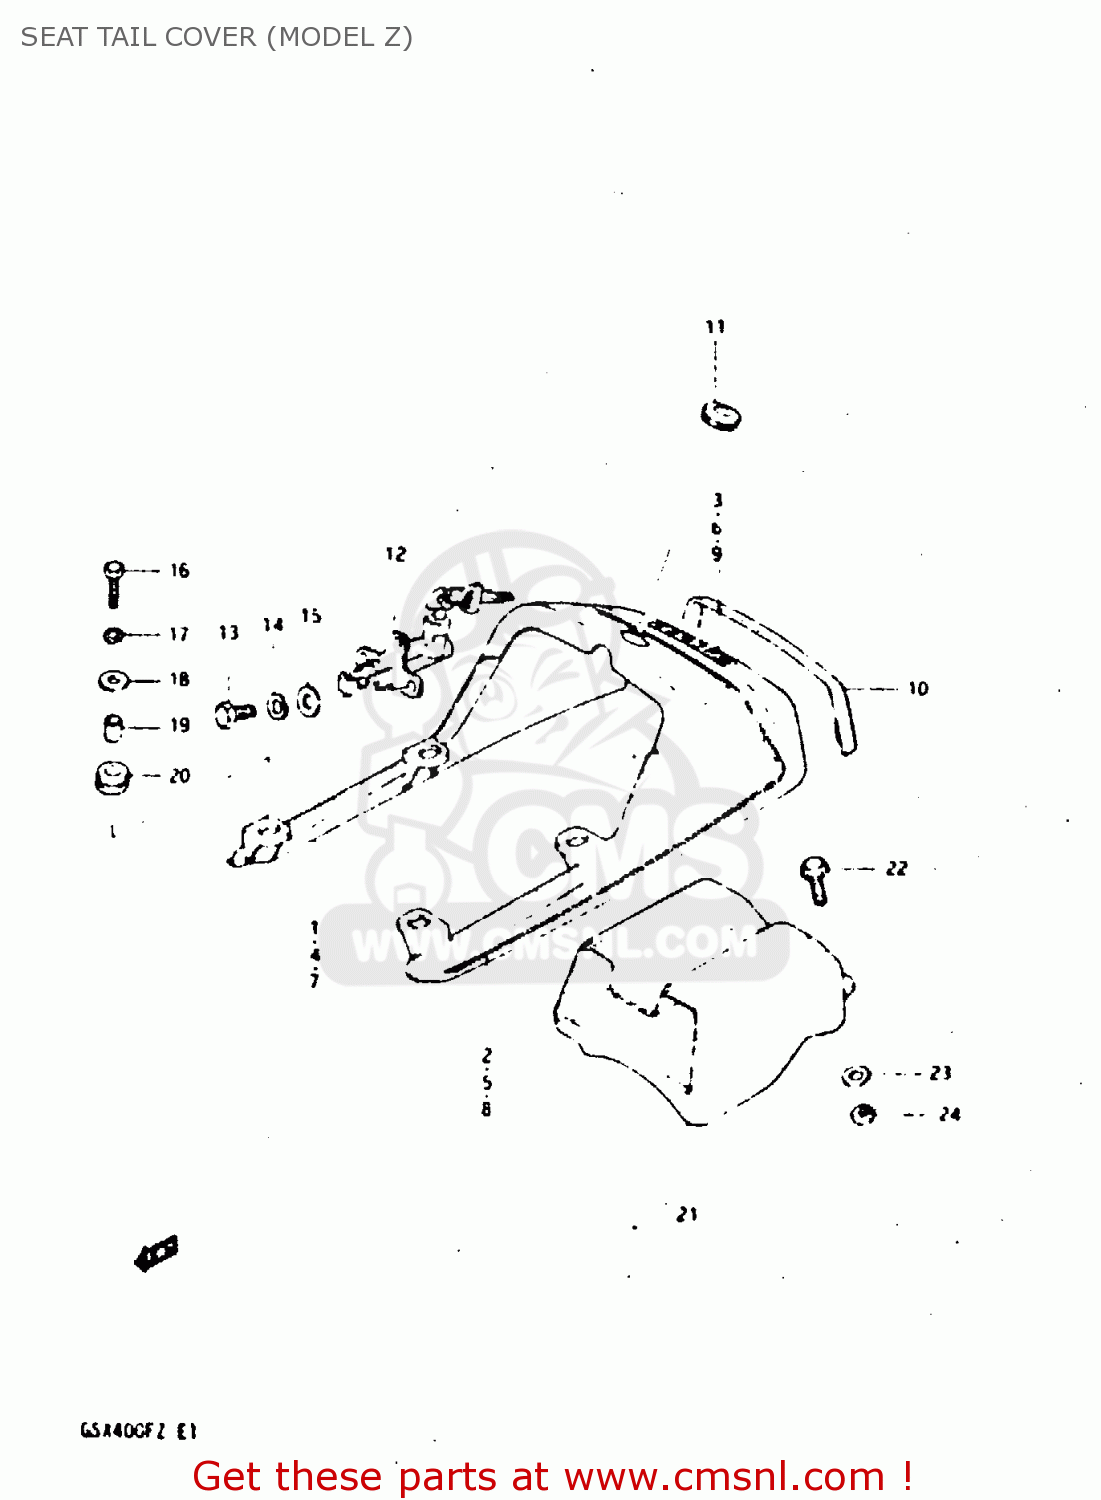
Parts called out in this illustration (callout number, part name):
1	COVER,SEAT TAI
2	TAPE SET
3	EMBLEM,SEAT TAIL(SILVER)
4	COVER, SEAT TAIL (SILVER)
5	TAPE SET
6	EMBLEM (RED)
7	COVER, SEAT TAIL (RED)
8	TAPE SET
9	EMBLEM,SEAT TAIL(SILVER)
10	CUSHION
11	GROMMET,SEAT LOCK HOLE
12	LOCK SET,SEAT
13	BOLT
14	LOCK WASHER
15	WASHER
16	BOLT
17	LOCK WASHER
18	WASHER(6,5X22X1.6)
19	SPACER(6.5X10.5X12)
20	CUSHION
21	BOX, SEAT TAIL
22	BOLT
23	WASHER
24	NUT
